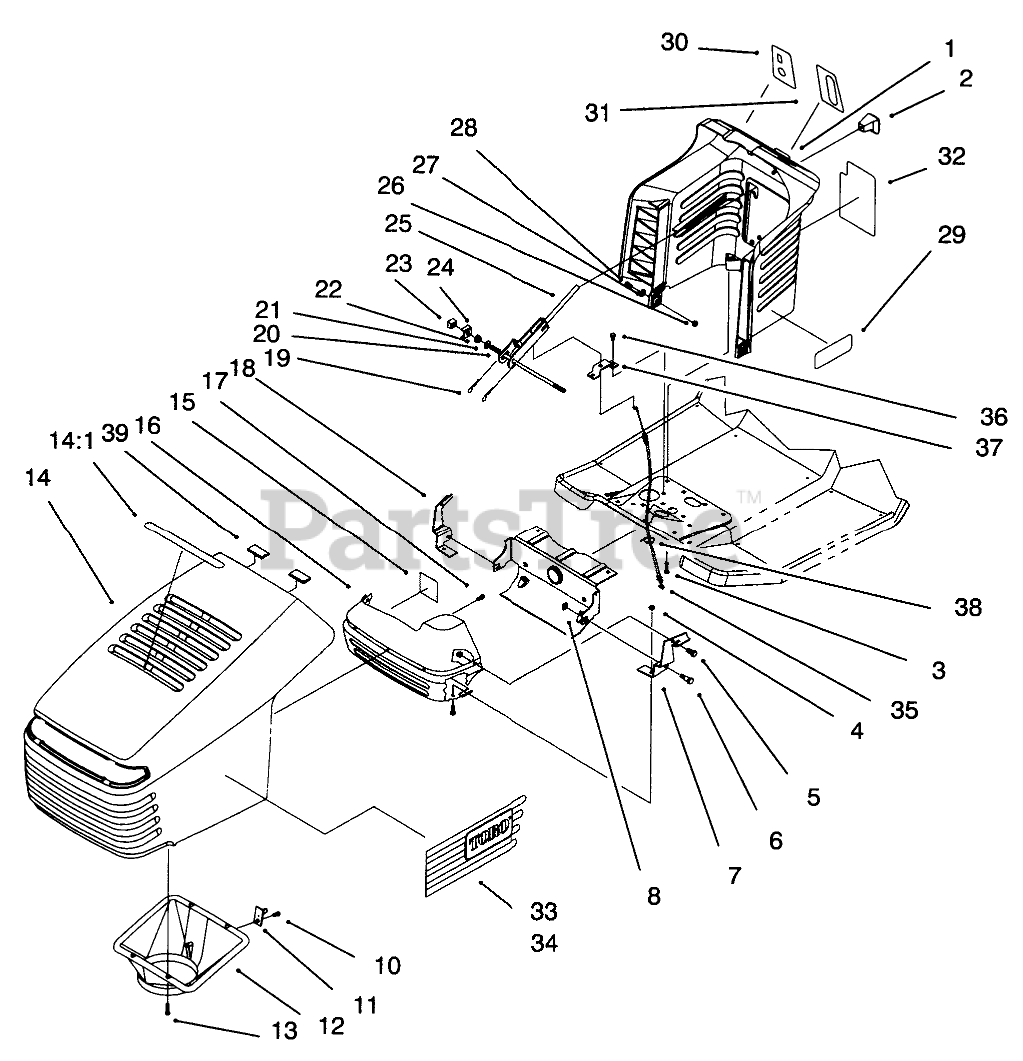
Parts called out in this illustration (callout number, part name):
1	Tower-Steering
2	KNOB-SHIFT
3	SCREW-HWH
4	NUT-LOCK, NI
5	SCREW-HH
6	BOLT-SHOULDER
7	BRACKET-PIVOT, LH HOOD
8	NUT-RETAINER
10	SCREW-HWH
11	LATCH-PIN
12	DUCT-AIR
13	SCREW-PLASTITE
14	Hood-Toro (Incl. Ref. #14:1)
14:1	DECAL-AIR DUCT
15	TAPE-FOIL
16	SHIELD-HEAT
17	SCREW-PLASTITE
18	BRACKET-PIVOT, RH HOOD
19	PIN-COTTER
20	ROD-TOWER PIVOT
21	WASHER-FLAT
22	NUT-FLANGE
23	NUT-WEDGE
24	ROD-CLAMP PIVOT
25	LEVER-DECK, ENGAGE
26	NUT-LOCK, NI
27	WASHER-PLAIN
28	SCREW-HH
29	DECAL-TOWER 1438 HXL
30	Decal-Ignition/Lights (Only On: 71193)
30	Decal-Ign/Lights (Only On: 71217)
31	Decal-Throttle (Only On: 71193)
31	Decal-Throttle (Only On: 71217)
32	Decal-Deck Engage (Only On: 71193)
32	Decal-Deck Engage (Only On: 71217)
33	DECAL - HOOD LEFT
34	DECAL - HOOD RIGHT
35	Cable-Deck Engage
36	SCREW-HWH
37	BRACKET-CABLE, UPPER
38	TIE-CABLE
39	FOAM-HOOD
